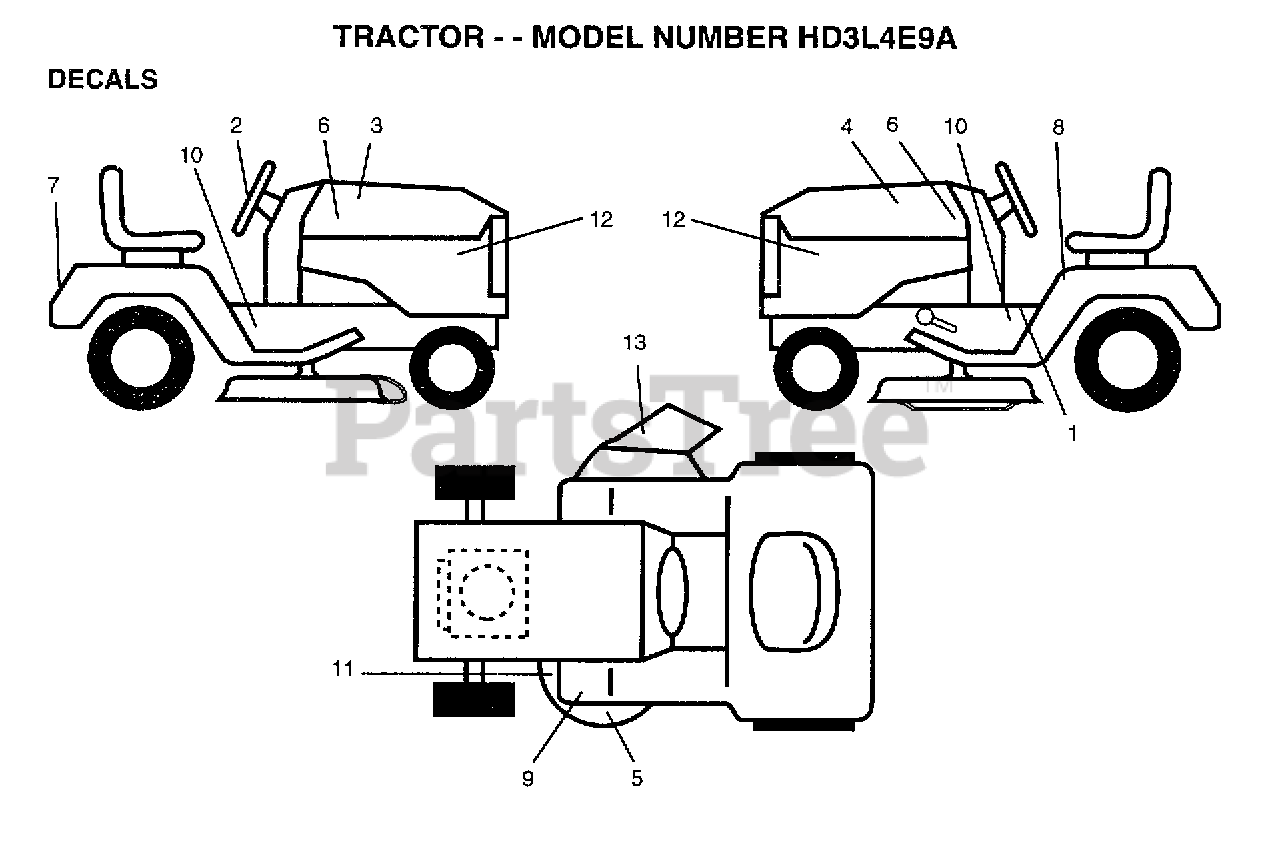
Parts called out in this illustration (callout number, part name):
1	DECAL.SADDLE.INST
2	DECAL.INST.WHL.ST
3	DECAL.HD.RH.16/42
4	DECAL.HD.LH.16/42
5	DECAL, HP ENGINE
6	DECAL.FEND.QUICKS
7	DECAL.FENDER.HDEP
8	DECAL CAUT FEND
9	DECAL CLUT/BRAKE
10	DECAL.SCH.DRV.42
11	DECAL.SCH.PRIM.42
12	DECAL.PNL.SD.HDPO
15	"DECAL, WARNING"
16	DECAL.DECK.MULCH.
17	DECAL.BTRY.DANGER
18	DECAL SEAT ACC
19	DECAL.PARTS.16HP
